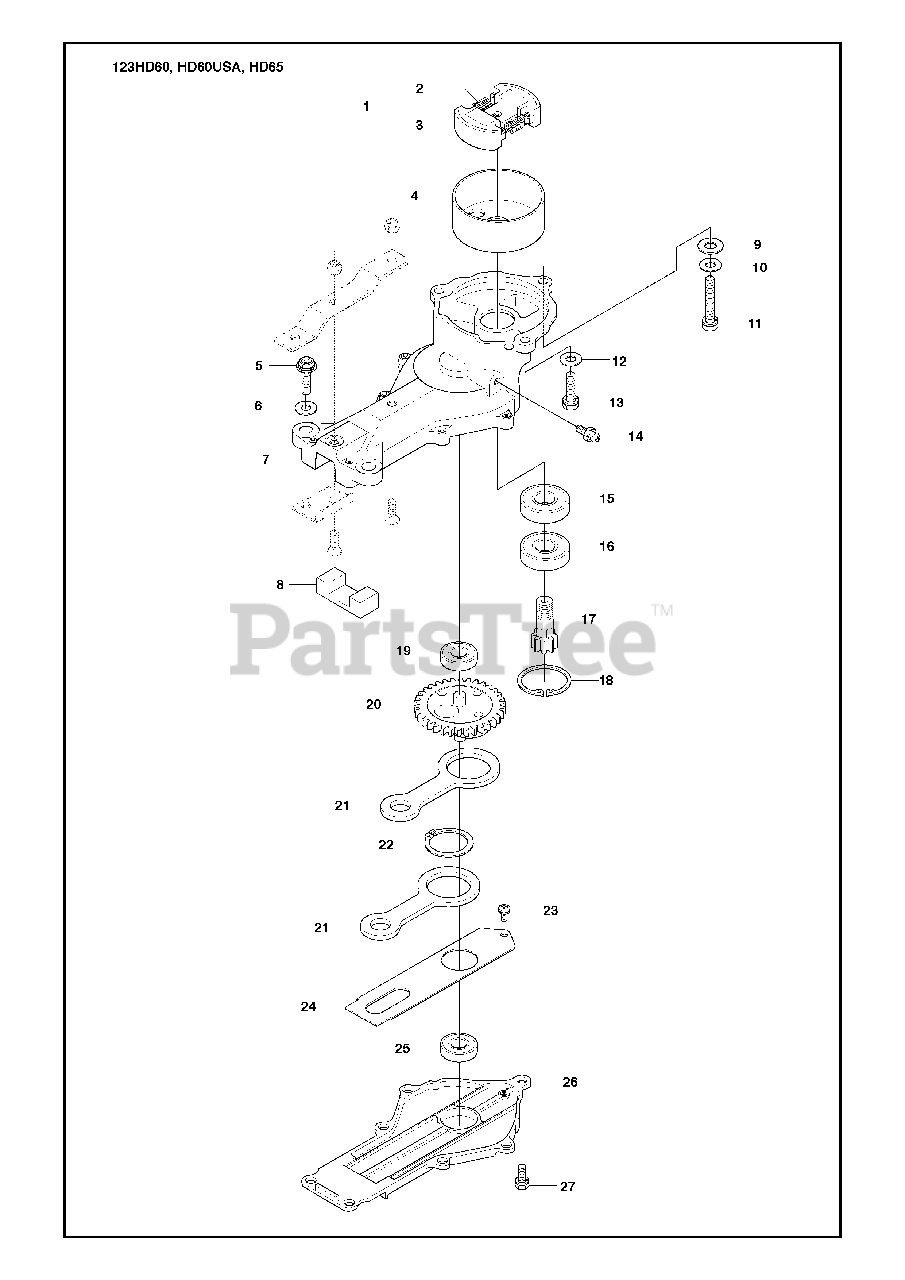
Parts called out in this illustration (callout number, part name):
4	CLUTCH DRUM
7	GEAR HOUSING
8	GREASE FILTER
9	WASHER - M6
11	BOLT FLANGE
14	GREASE FITTING
18	RETAINING RING
20	CRANK GEAR
22	RETAINING RING
